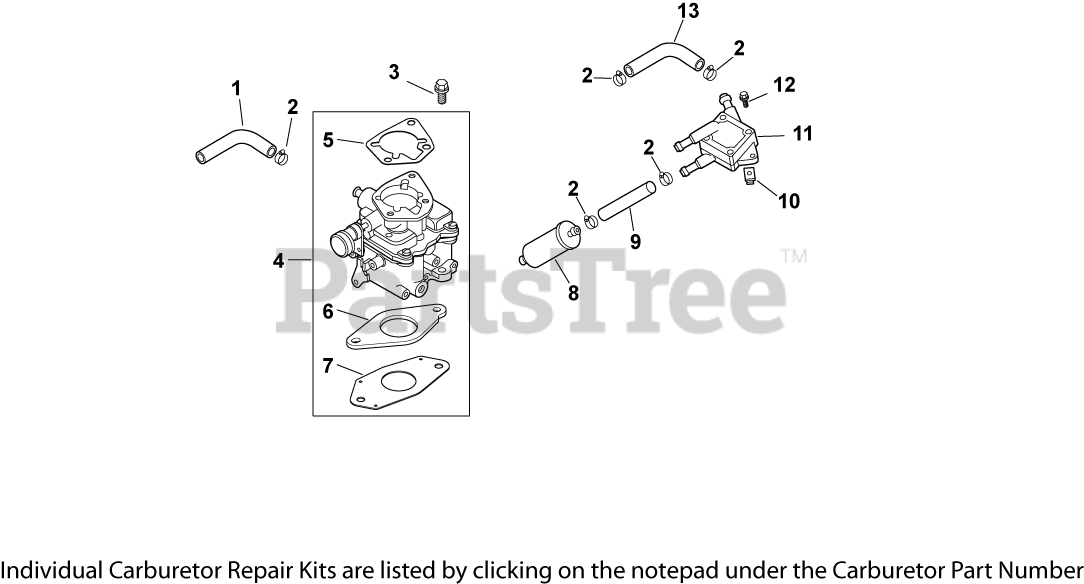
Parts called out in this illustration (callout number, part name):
1	LINE, FLEXIBLE FUEL - DISCONTINUED
2	CLAMP, HOSE (KM)-USE 25 237 31-S
3	SCREW - USE 25 086 124-S
4	KIT, CARBURETOR W/GASKETS
5	GASKET, AIR CLEANER BASE
6	GASKET, CARBURETOR
7	GASKET, CARBURETOR
8	FILTER, FUEL (9-12 MICRON)-USE 24 050 13
9	LINE, FLEXIBLE FUEL 9.30"-USE 25 111 81-
10	NUT, PLASTIC (KM)-USE 25 100 37-S
11	PUMP, FUEL
12	SCREW, TAP M6X1.7X18
13	LINE, FLEXIBLE FUEL 15 1/2"
